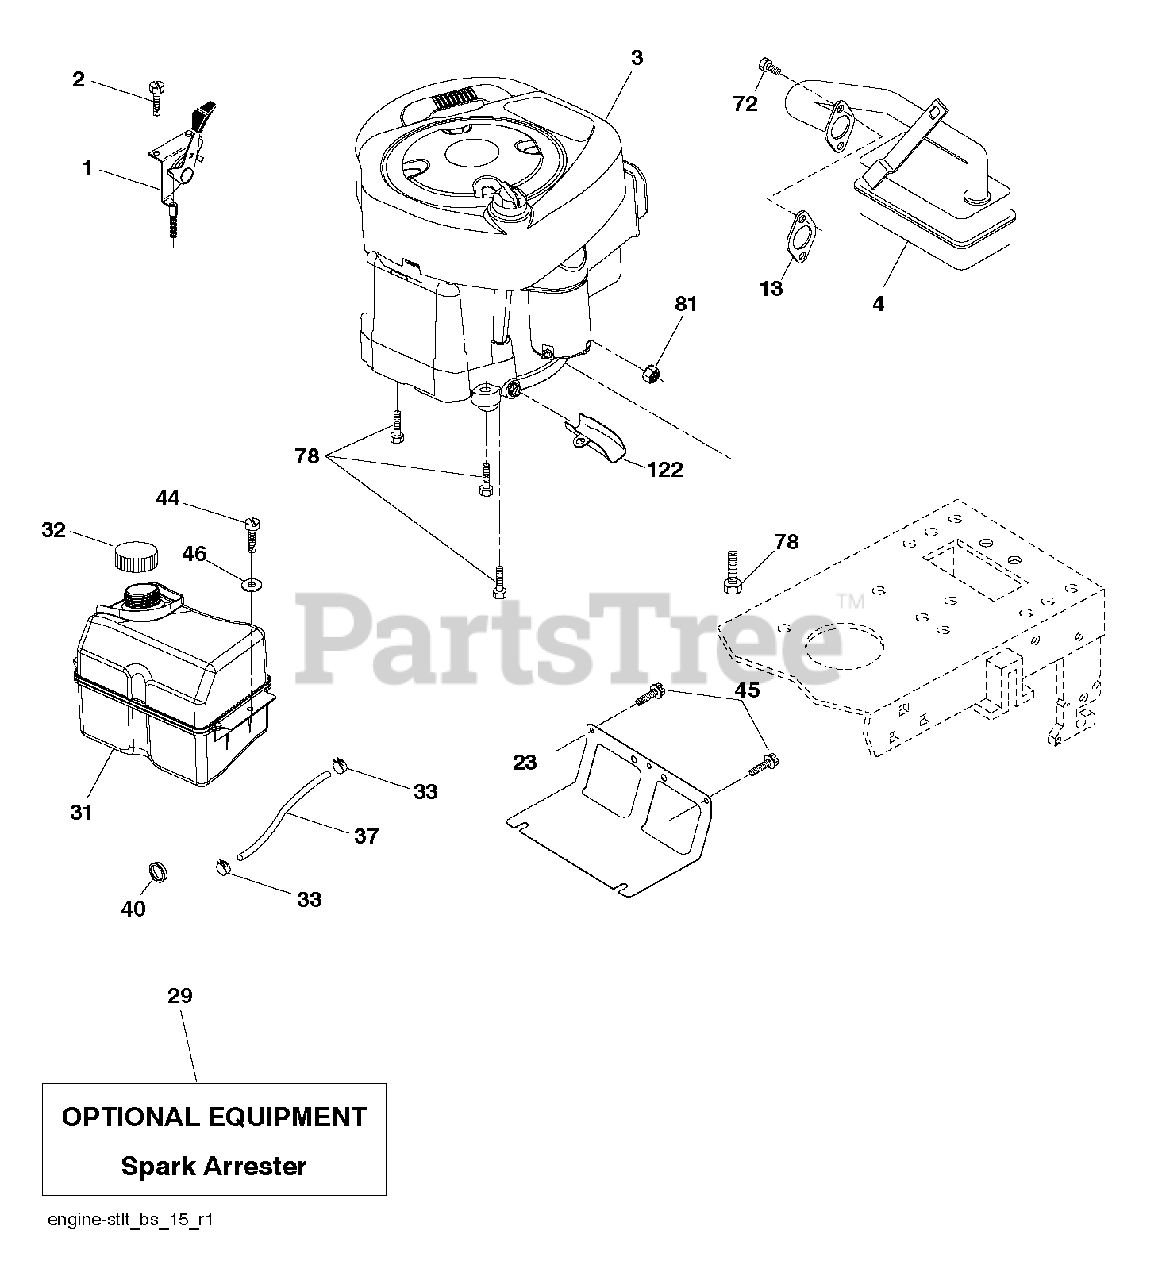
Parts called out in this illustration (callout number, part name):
1	CONTROL.THROTTLE/CHOKE.BLACK
4	MUFFLER.LT.BRIGGS.14HP.IC/OHV
23	SHIELD.BROWNING.DBR.GUARD
29	KIT.SPARK ARRESTOR(392390 B&S)
31	RP TANK FUEL FRT 1.5 GAL
32	CAP ASM.FUEL.2.25"FR.
33	HOSE CLAMP
37	LINE.FUEL.20"FRONT.EMI
40	GROMMET T
44	SCREW HEXWSHR 1/4-20X3/4
45	SCREW, 3/8-16X3/4
46	WASHER
72	SCREW.SOCKET HD.5/16-1
78	SCREW.3/8-16
81	NUT
122	EXTENSION DRAIN OIL
